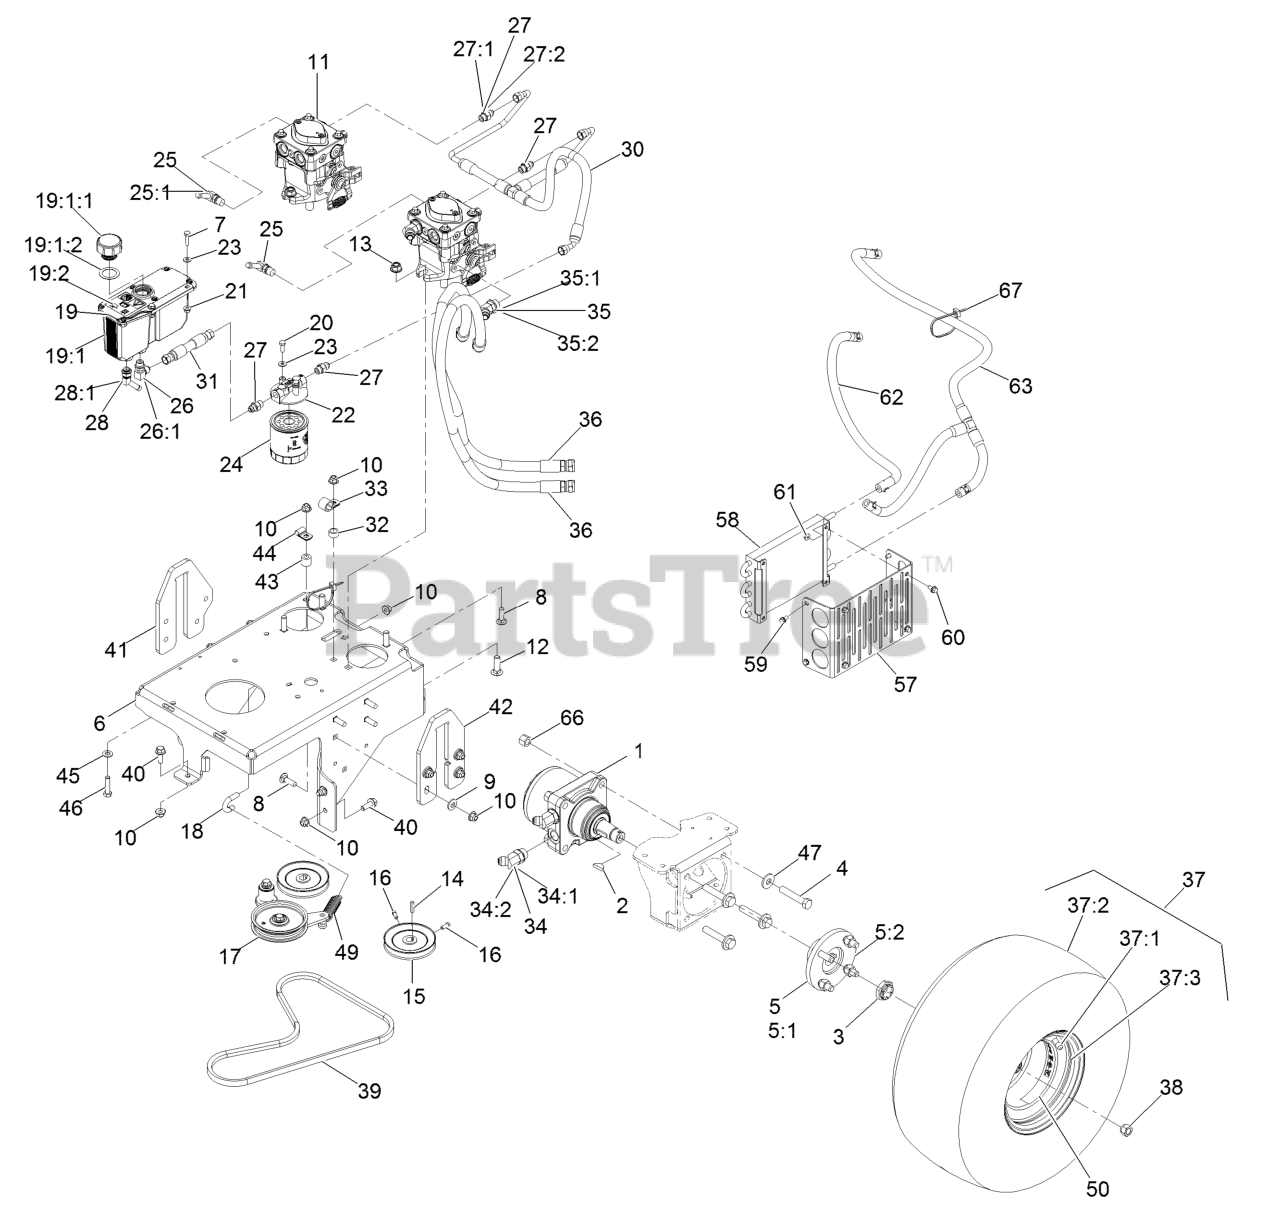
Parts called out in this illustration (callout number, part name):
1	Motor-Wheel
2	Key-Woodruff
3	Locknut
4	Screw-HH 1/2-13 X 2 3/4
5	Wheel Hub / Stud ASM
5:1	Hub-Wheel
5:2	Stud-Type, Drive
6	Base, Engine [red]
7	Screw-HH 1/4-20 X 1
8	Bolt-Carriage 3/8-16 X 1 1/4
9	Washer-Spring Disc 3/8
10	Nut-Nyloc 3/8-16 Flg
11	Pump - Hydraulic
12	Bolt-Carriage 7/16-14 X 1 1/2
13	Nut-HF, NI
14	Key-5Mm X 5Mm X 25Mm
15	Pulley-Pump
16	Setscrew-SQH 1/4-20 X 5/8
17	Pump Idler ASM
18	Anchor, Spring
19	Reservoir ASM
19:1	Reservoir-HYD
19:1:1	Cap-Reservoir, HYD
19:1:2	Gasket-Cap
19:2	Decal-Warning
20	Screw-HH 1/4-20 X 3/4
21	Nut-Hex 1/4-20 Side Lock
22	Filter-Head
23	Washer-1/4 SAE
24	Element, Oil Filter
25	Fitting-Elbow, 90
25:1	O-Ring
26	Fitting-Elbow, 90 DEG
26:1	O-Ring
27	Adapter-Straight
27:1	O-Ring-SAE #6
27:2	O-Ring-37 Flare #6
28	Fitting-Barbed, 45 DEG
28:1	O-Ring
30	Hose Assembly - Charge
31	HYD Hose ASM
32	Spacer-Wheel
33	Clip-Loom 5/8
34	Fitting-HYD, 45 DEG
34:1	O-Ring-SAE #10
34:2	O-Ring-37 Flare #8
35	Fitting-HYD, 45 DEG
35:1	O-Ring-SAE #8
35:2	O-Ring-37 Flare #8
36	HYD Hose ASM
37	Wheel/Tire ASM
37:1	Rim-8 Inch
37:3	Stem-Valve
38	Nut-Lug 1/2-20
39	Belt-V
40	Screw HHF 3/8-16 X 1
41	Plate-Lift, RH
42	Plate, Lift LH
44	Clip-Tube
45	Washer-3/8 SAE
46	Screw-HH 3/8-16 X 1 1/2
47	Washer-Spring Disc 1/2
49	Spring-Extension
50	Decal-Torque, Wheel Hub Lug
57	Bracket, Cooler Mounting
58	Cooler-Oil
59	Screw-HWH 1/4-20 X 1/2 Taptite
60	Screw-HHF
61	Nut-Keps
62	Hose-Hydraulic
63	Hose ASM-HYD LP 3/8
66	Nut-Nyloc 1/2-13
67	Tie-Cable
